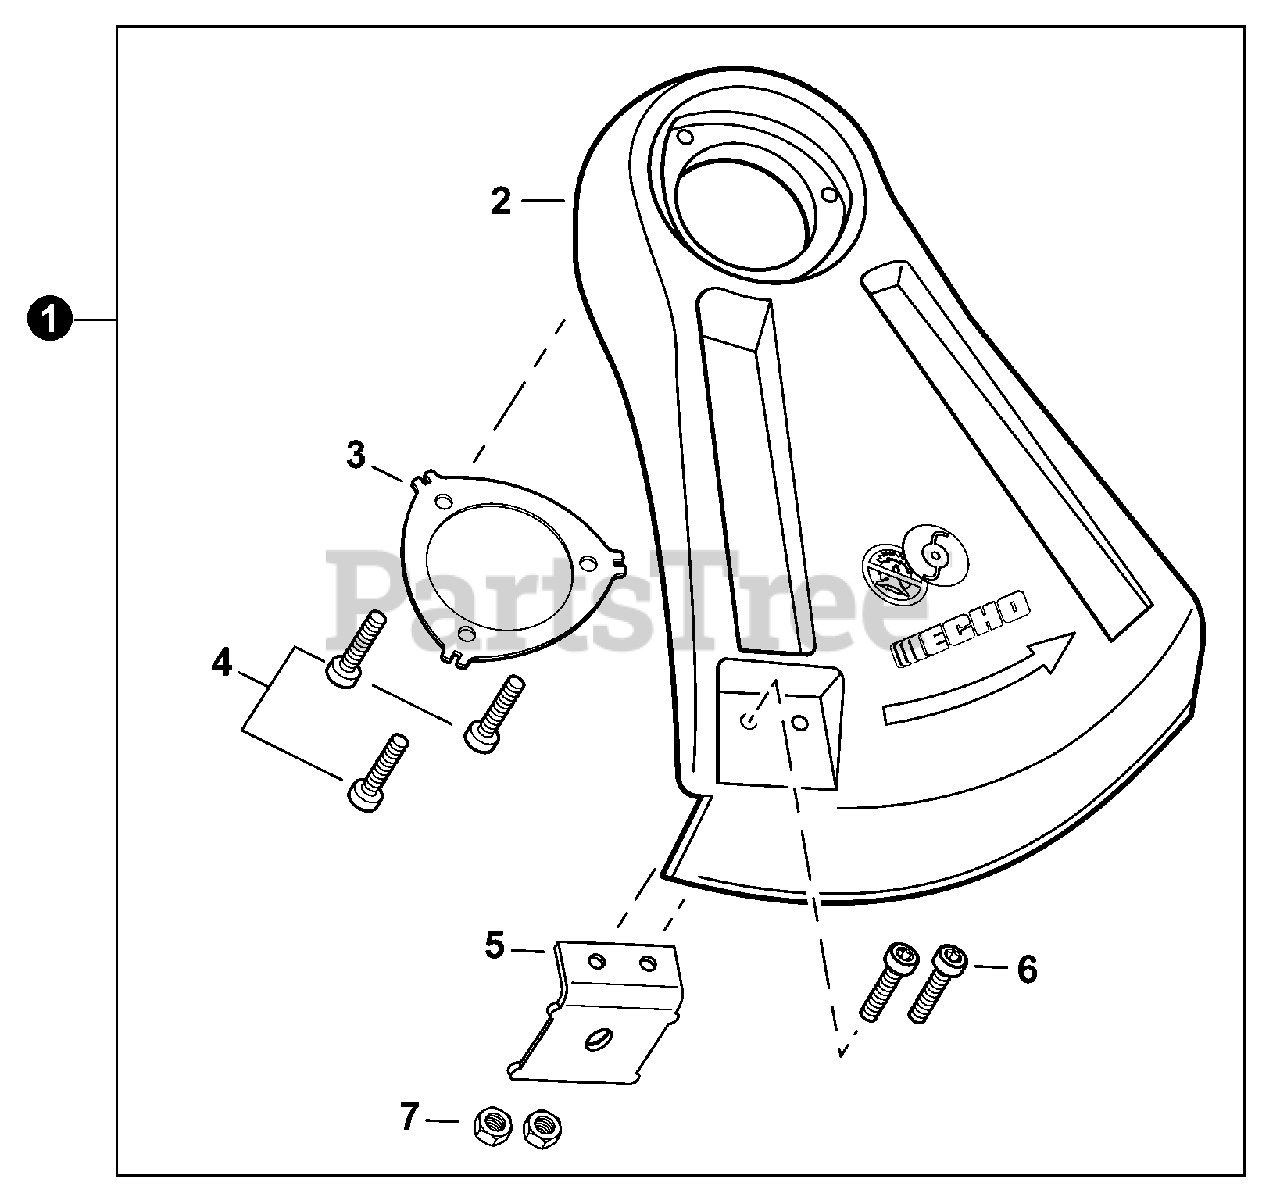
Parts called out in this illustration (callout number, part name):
1	DEBRIS SHIELD KIT
2	SHIELD, DEBRIS PLASTIC
3	PLATE, SHIELD
4	BOLT, TORX 5×16
5	CUTTER, LINE
6	BOLT, TORX 5×12
7	NUT M5
